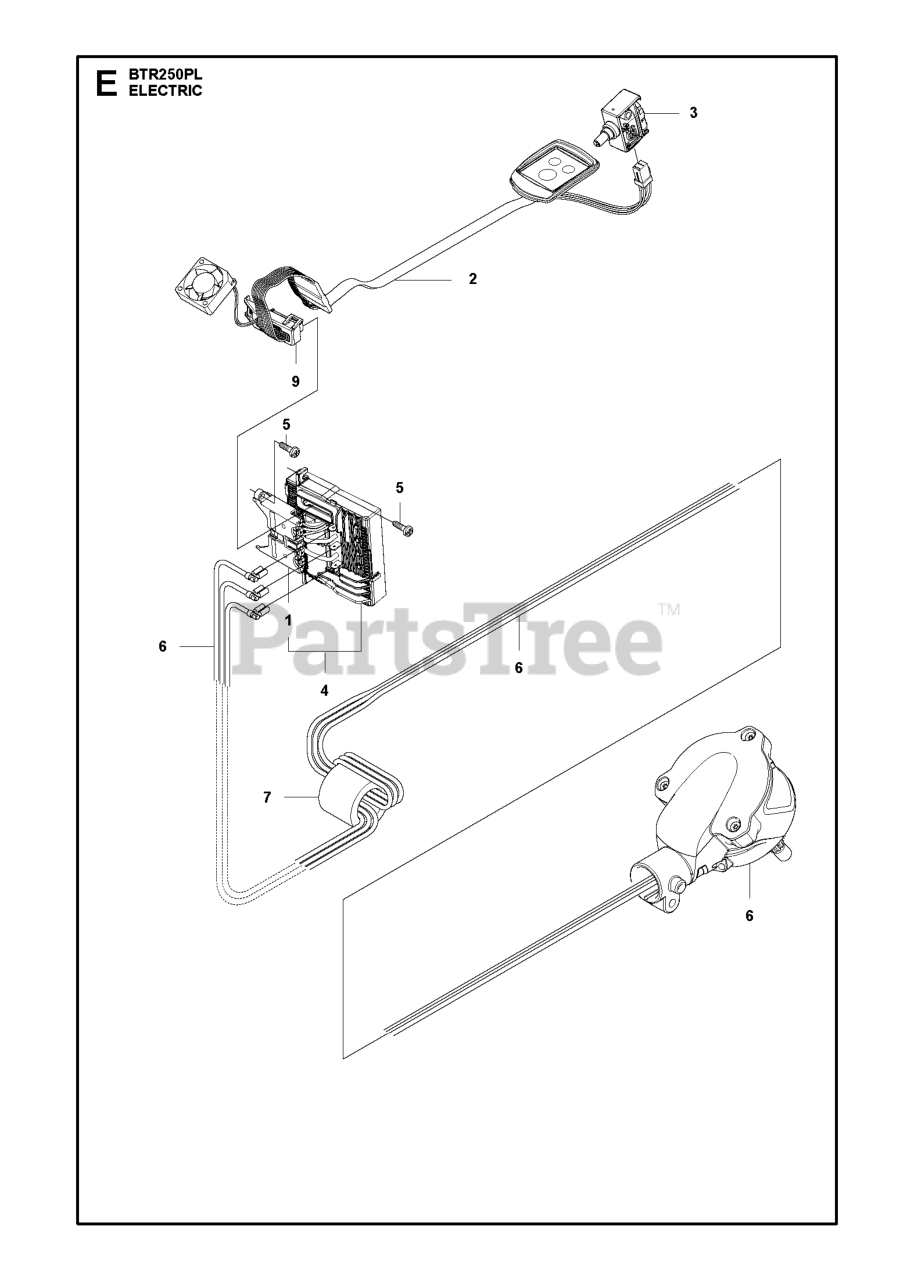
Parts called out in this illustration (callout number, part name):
1	CONNECTOR BATTERY
2	WIRING ASSY MAIN T2 ZENOAH/RED
3	TRIGGER SWITCH IPX4
4	CONTROL UNIT
5	SCREW CCRPANT
6	MOTOR ASSY BLDC ZENOAH/REDMAX
7	FERRITE CORE
